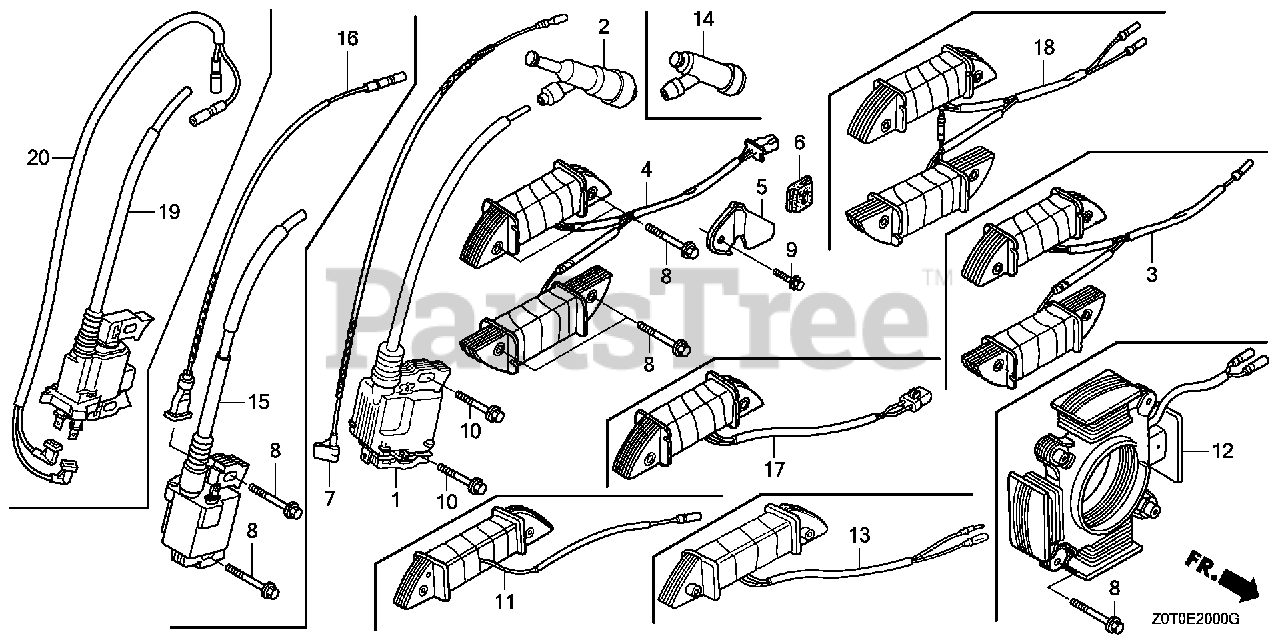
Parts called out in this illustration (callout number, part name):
1	COIL ASSY., IGNITION (TEC)
2	CAP ASSY., NOISE SUPPRESSOR (NGK)
2	CAP ASSY., NOISE SUPPRESSOR (TEC)
3	COIL ASSY., LAMP (12V/50W)
5	CLAMP, WIRE
6	GROMMET, WIRE
7	WIRE, STOP SWITCH (370MM)
8	BOLT, FLANGE (6X28) (CT200)
9	BOLT, FLANGE (5X10) (CT200)
10	BOLT, FLANGE (6X25) (CT200)
